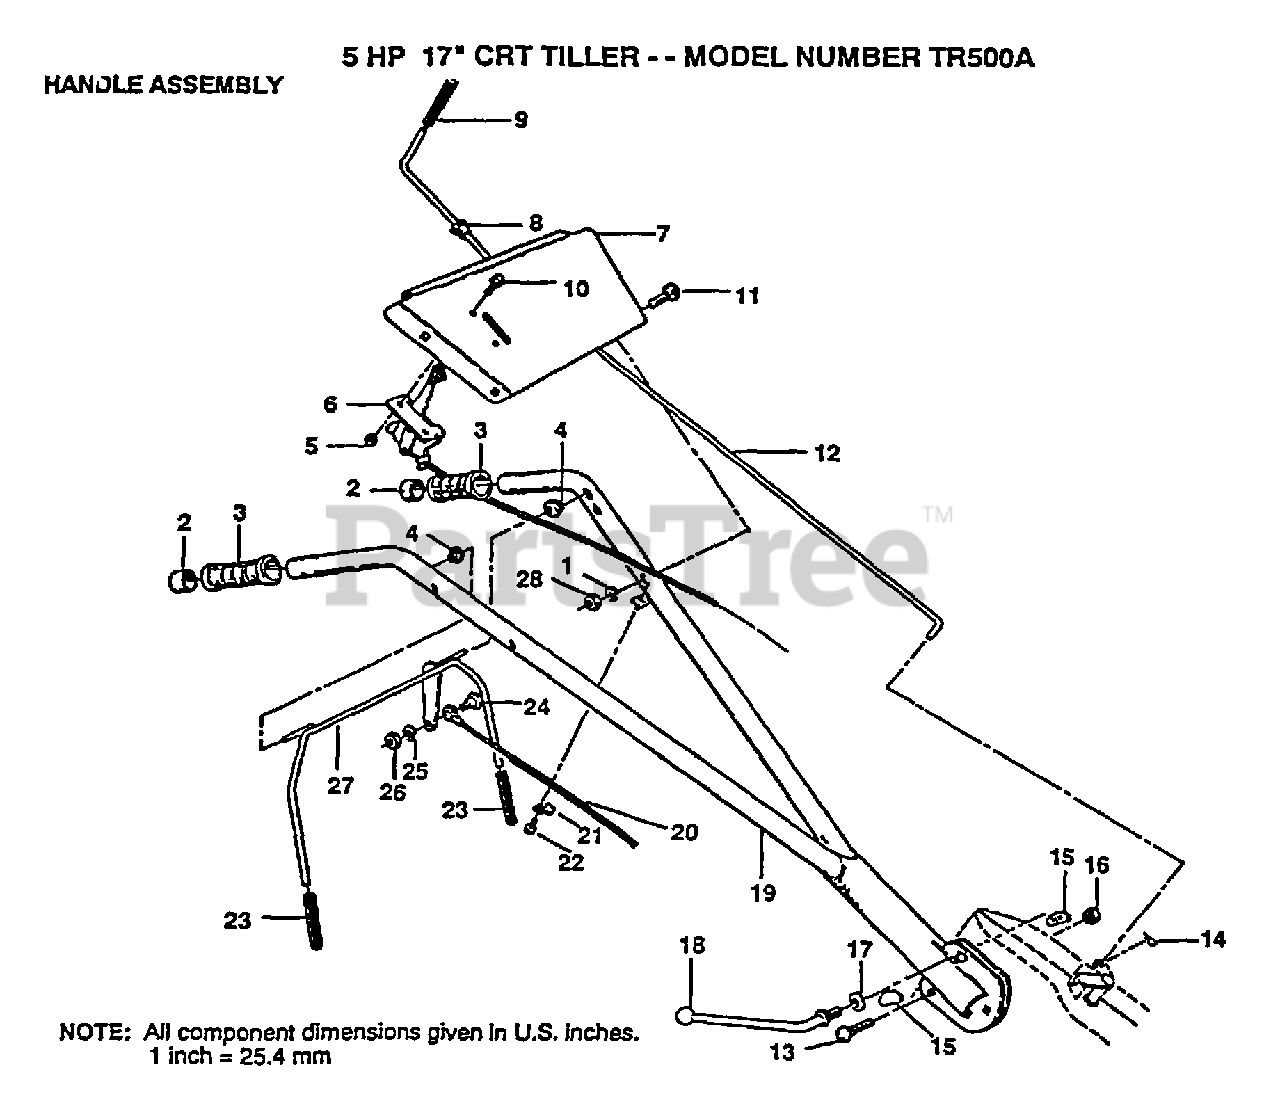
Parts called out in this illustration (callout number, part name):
1	LOCKWASHER
2	CAP CRT
6	"CONT,THROTTLE"
8	BUSHING
9	GRIP TI
10	SCREW
11	BOLT CARRIAGE CRT
12	ROD SHIFT CRT
13	BOLT D
14	RETAINER M
15	LOCK CRT
17	WASHER CRT
18	LEVER LOCK CRT
20	CABLE.CLUTCH.CRT
21	CONDIUT CLIP T
23	GRIP BAR CRT
24	SHOULDER BOLT ST
25	LOCKWASHER
27	HANDLE BAR CRT
